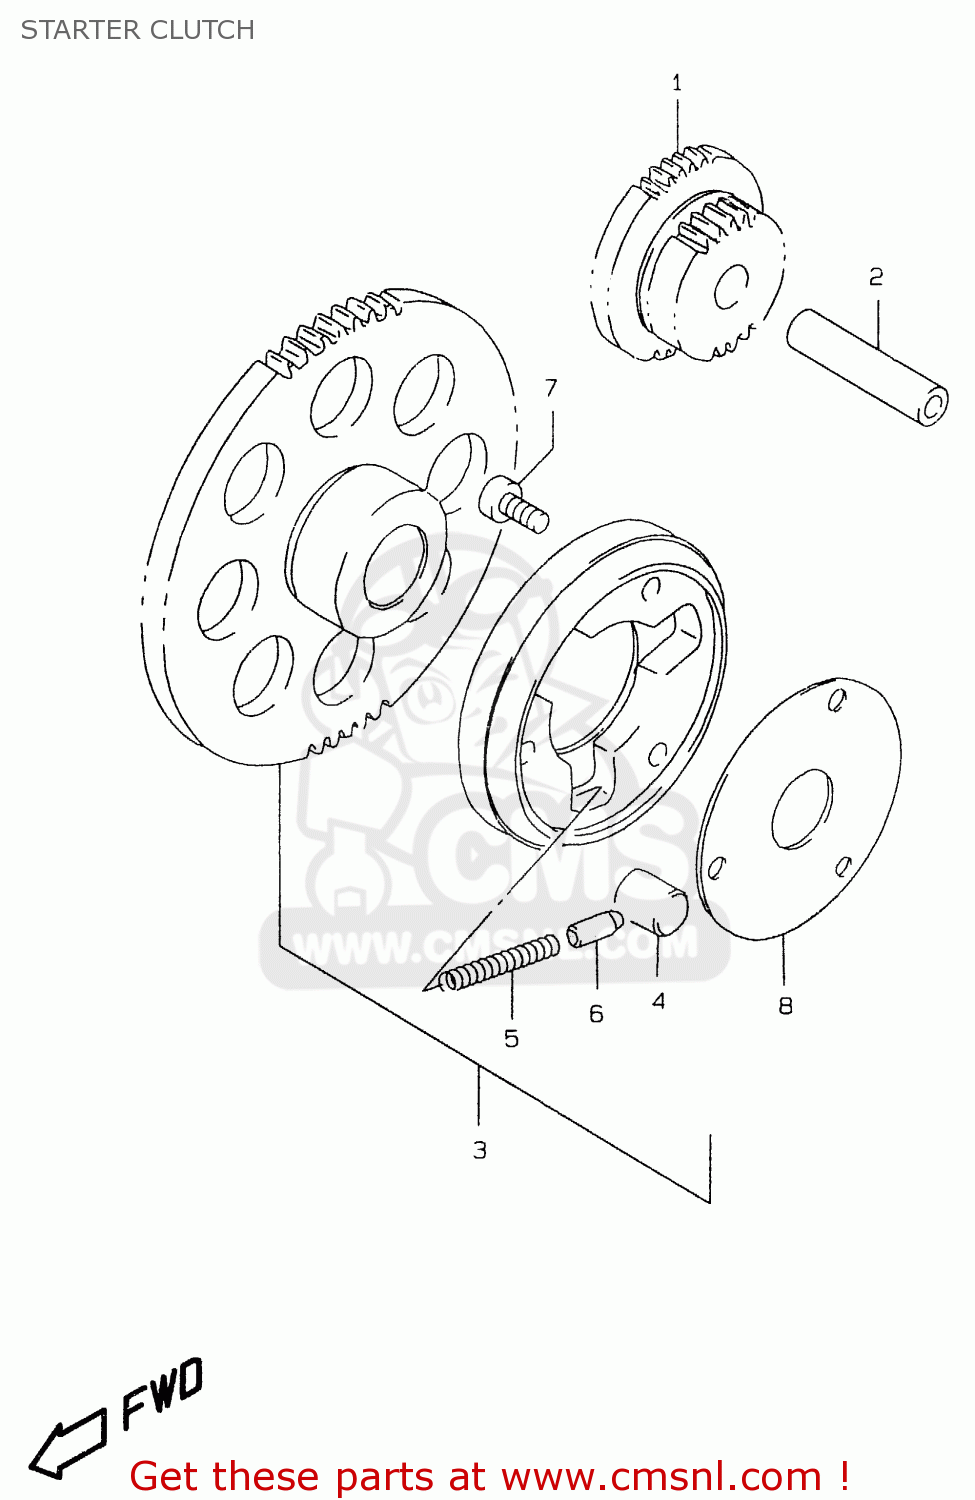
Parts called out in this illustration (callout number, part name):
1	GEAR,STARTER IDLE
2	PIN(7.4X13X56)
3	CLUTCH SET,STARTER
4	ROLLER(15X13)
5	SPRING
6	PIECE,PUSH
7	BOLT
8	SHIM,STARTER CLUTCH HUB
